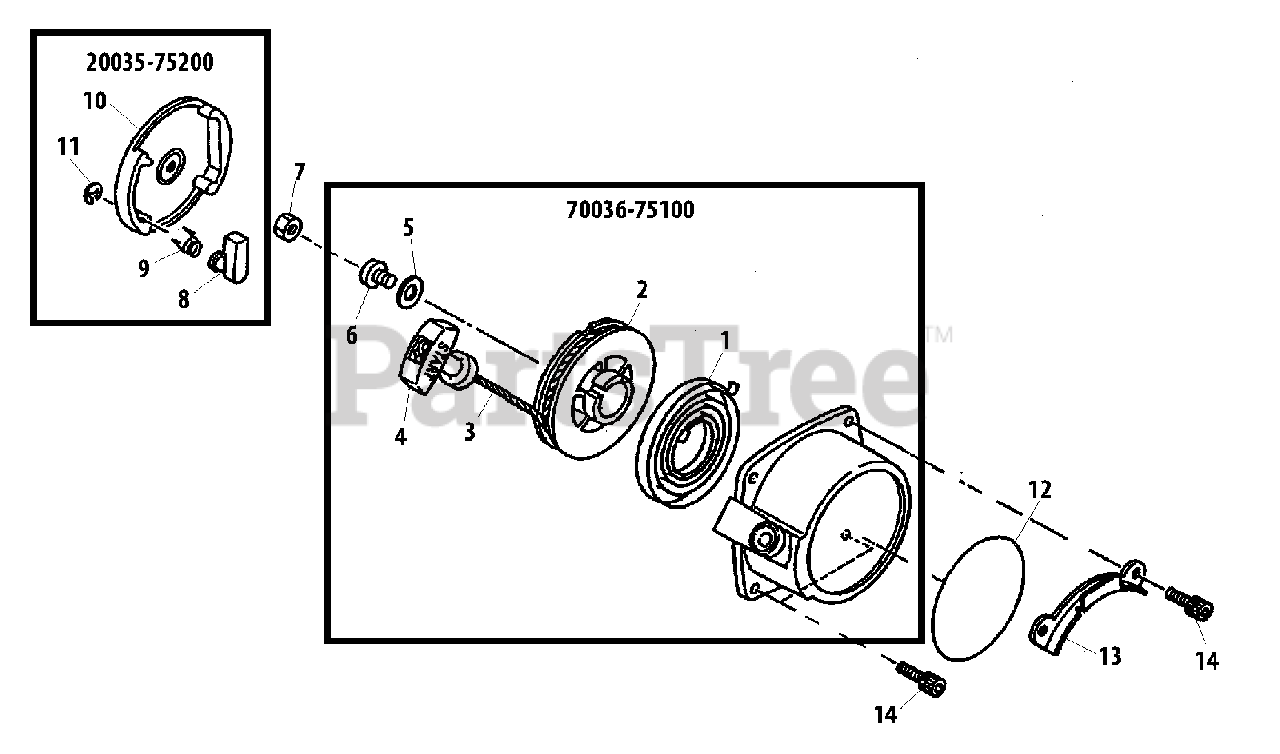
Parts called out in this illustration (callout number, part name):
1	SPRING, RECOIL
2	REEL, ROPE
3	ROPE, STARTER
4	GRIP, STARTER
5	WASHER 5
6	SCREW 5
7	NUT
8	RATCHET
9	SPRING, RETURN
10	PULLEY, STARTER
11	E-RING
12	LABEL, RECOIL STARTER
13	BRACKET
14	BOLT, ADHESIVE M4×16
20035-75200	PULLEY ASSY, STARTER
70036-75100	STARTER ASSY, RECOIL
